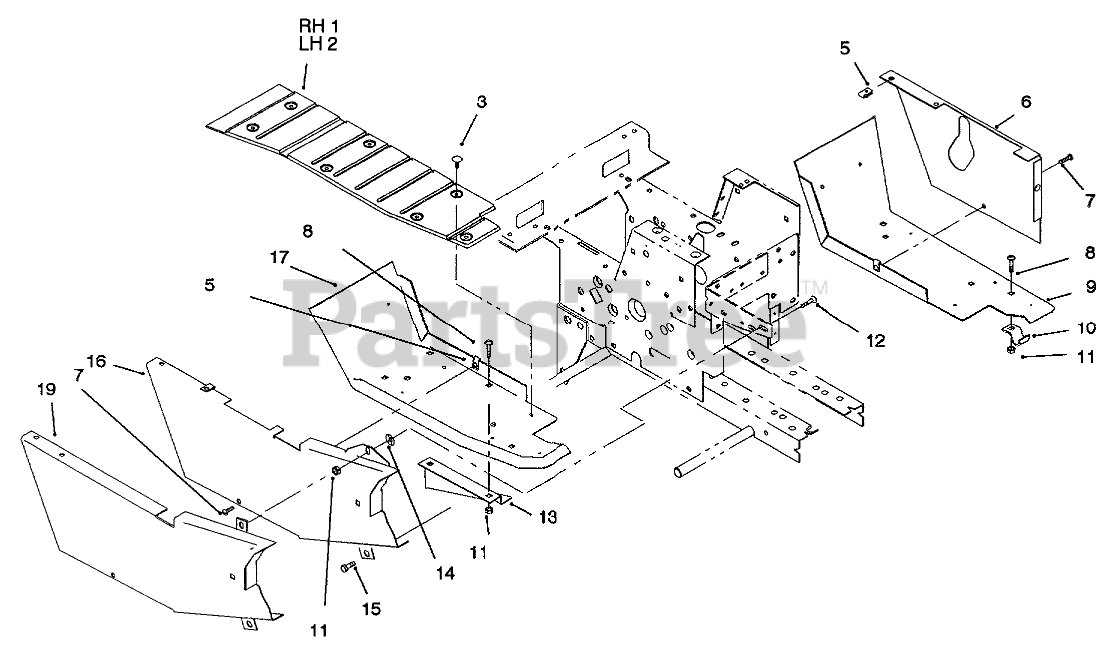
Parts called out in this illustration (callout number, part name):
1	PAD-FOOT RH
2	PAD-FOOT LH
3	FASTENER-PANEL
6	COVER-L.H (RED)
7	SCREW-PPH
8	BOLT-CARR
9	FOOTREST-LH
10	BRACKET
11	NUT-LOCK, NI
12	BOLT-CARR
14	NUT-PUSH
15	Bolt
16	GUARD WA - BELT (RED)
17	FOOTREST-RH
